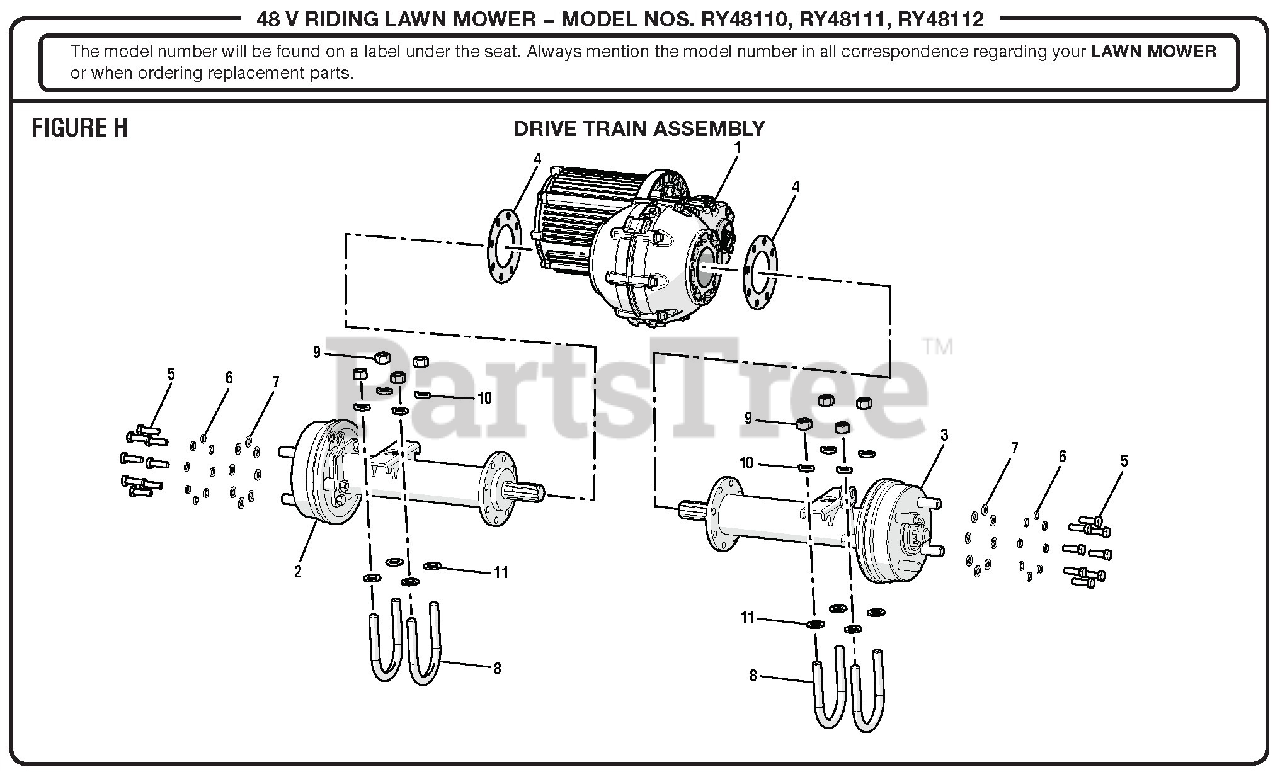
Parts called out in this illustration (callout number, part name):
1	Transaxle
2	Left Rear Axle
3	Right Rear Axle
4	Transmission Gasket
5	Bolt (M8 x 25 mm)
6	Lock Washer (8 mm)
7	Washer (OD16 x ID8.4 x 1.6t)
9	Hex Nut (M12 x 1.75 mm)
10	Spring Washer (OD20 x ID12.4 x 2t)
11	Washer (OD24 x ID13 x 2.5t)
